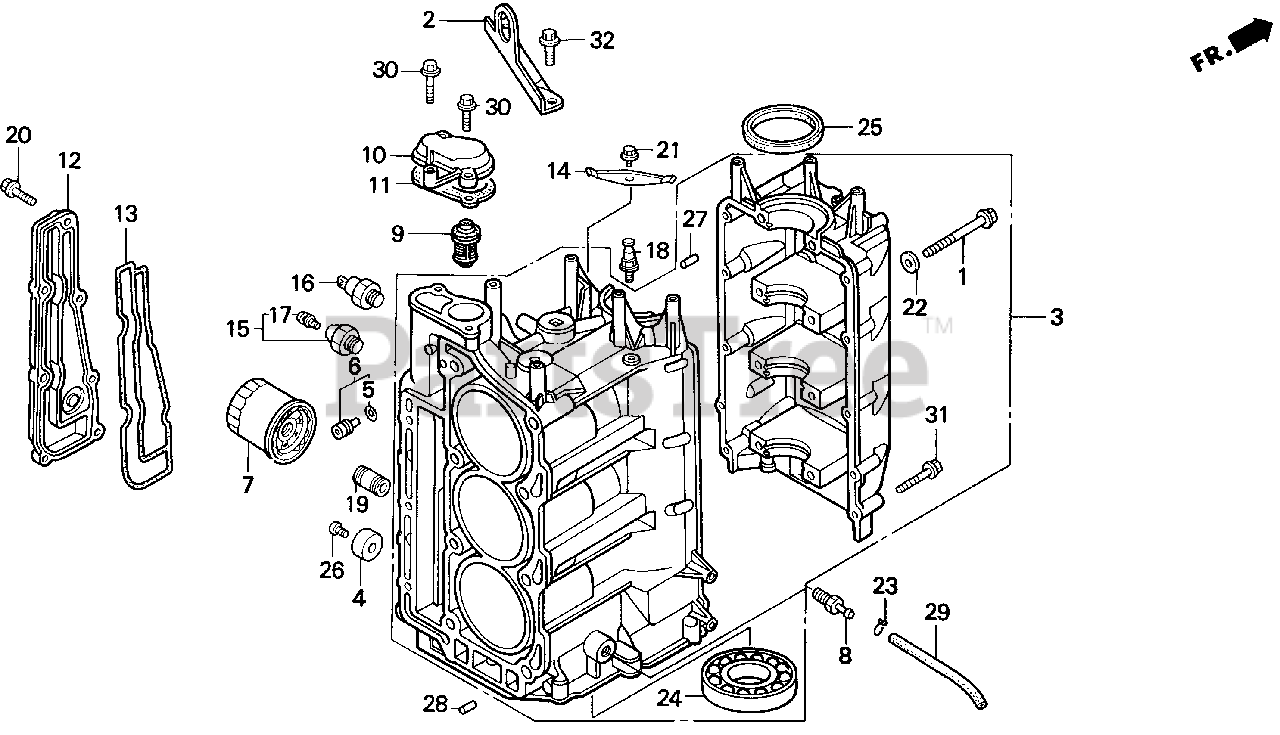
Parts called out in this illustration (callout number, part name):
1	BOLT, FLANGE (8X95)
2	HANGER, ENGINE
3	BLOCK ASSY., CYLINDER *NH8* (DARK GRAY)
4	METAL, ANODE
5	O-RING (4.8X1.9)
6	ORIFICE ASSY., OIL PASSAGE
7	FILTER, OIL (DENSO)
8	JOINT, WATER HOSE
9	THERMOSTAT ASSY. (72 DEGREES C)
10	COVER, THERMOSTAT *NH8* (DARK GRAY)
11	GASKET, THERMOSTAT COVER
12	COVER, WATER JACKET *NH8* (DARK GRAY)
13	GASKET, WATER JACKET COVER
14	HOLDER, WIRE (A)
15	SWITCH, OIL PRESSURE
16	SWITCH ASSY., THERMOSTAT
17	SCREW-WASHER (4X8)
18	BOLT, TIMING BELT ADJUST SPRING
19	HOLDER, OIL FILTER
20	BOLT, FLANGE (6X22)
21	BOLT, FLANGE (6X12)
22	WASHER, PLAIN (8MM)
23	CLIP, TUBE (B8)
24	BEARING, RADIAL BALL (6005)
25	OIL SEAL (56X70X8)
26	SCREW, PAN (6X18)
27	PIN, DOWEL (10X12)
28	PIN A, DOWEL (12X16)
29	BULK HOSE, VACUUM (4.5X1000) (4.5X125)
30	BOLT, FLANGE (6X20)
31	BOLT, FLANGE (6X40)
32	BOLT, FLANGE (8X18)
